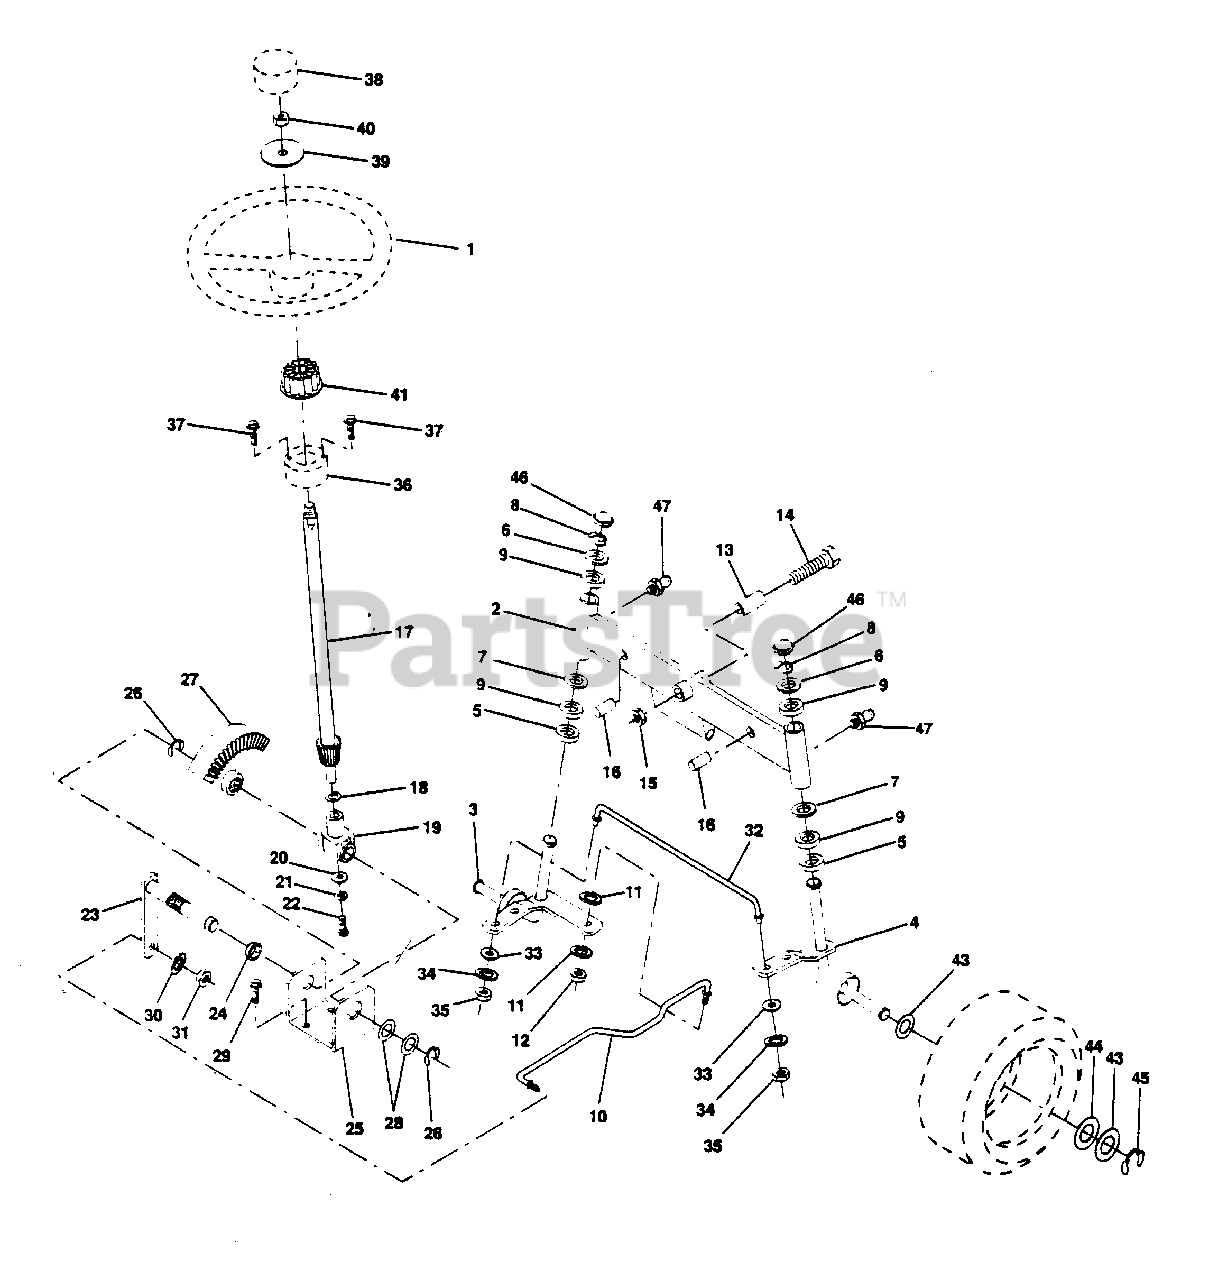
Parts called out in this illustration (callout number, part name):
1	Wheel Steering Auto Blk (AYP part number)
2	Axle Asm Fr LT W/gzks 38/42 (AYP part number)
3	Spindle Asm LH (AYP part number)
4	Spindle Asm RH
5	Bearing Race Thrust Harden (AYP part number)
6	Washer 25/32 X 1-5/8 X 16 Ga (AYP part number)
7	Washer 27/32 X 1-1/4 X 16 Ga (AYP part number)
8	Ring Klip #t5304-75 (AYP part number)
9	Bearing Col Strg Blk (AYP part number)
10	Link Drag Sol Ball Jt 20 064 (AYP part number)
11	Washer Lock Hvy Hlcl Spr 3/8 (AYP part number)
12	Nut Fin Hex 3/8-24 Unf (AYP part number)
13	Spacer Bearing Axle Front (AYP part number)
14	Bolt Hex 5/8-11 Unc X 3-1/2 (AYP part number)
15	Nut Lock Flange 5/8-11 Unc (AYP part number)
16	Pin Axle 5/8 X 1 55/1 54 Lg (AYP part number)
17	Shaft Asm Strg 20 31 x 3/4 YP YT (AYP part number)
18	Washer Thrust 515x 750x 033 (AYP part number)
19	Support Shaft (AYP part number)
20	Washer Shim 1/4 X 5/8 X 062 (AYP part number)
21	Washer Lock Hvy Helical 1/4 (AYP part number)
22	Screw Hex Socket 1/4-20 X 5/8 (AYP part number)
23	Shaft Asm Pittman (AYP part number)
24	Nyliner Snap In (AYP part number)
25	Bracket Steering (AYP part number)
26	Ring Klip #t5304-75 (AYP part number)
27	Gear Sector (AYP part number)
28	Bearing Race Thrust Harden (AYP part number)
29	Screw Thdrol 3/8-16x3/4 Ty-tt (AYP part number)
30	Washer Lock Hvy Hlcl Spr 3/8 (AYP part number)
31	Nut Fin Hex 3/8-24 Unf (AYP part number)
32	Rod Tie Wire Form 19 75 Elec (AYP part number)
33	Washer 11/32 x 3/4 x 16 Ga. (AYP part number)
34	Washer, Lock Hvy Hlcl Spr 5/16 (AYP part number)
35	Locknut 5/16-24 Unf (AYP part number)
36	Bushing Strg Blk 742/747 Id (AYP part number)
37	Screw Slftp #10-16 X 1/2 Ty-b (AYP part number)
38	Insert Cap Strg Wh Aut Gen Blk (AYP part number)
39	Washer 53 X 2 25 X 160 Zinc (AYP part number)
40	Nut Hex Jam Toplock 1/2-20 Unf (AYP part number)
41	Adapter Wheel Strg 758/ 753id (AYP part number)
43	Washer 25/32 X 1 1/4 X 16 Ga (AYP part number)
44	Washer 25/32 X 1-5/8 X 16 Ga (AYP part number)
45	Ring Klip #t5304-75 (AYP part number)
46	Cap Spindle Fr Top Blk (AYP part number)
47	Fitting Grease (AYP part number)
